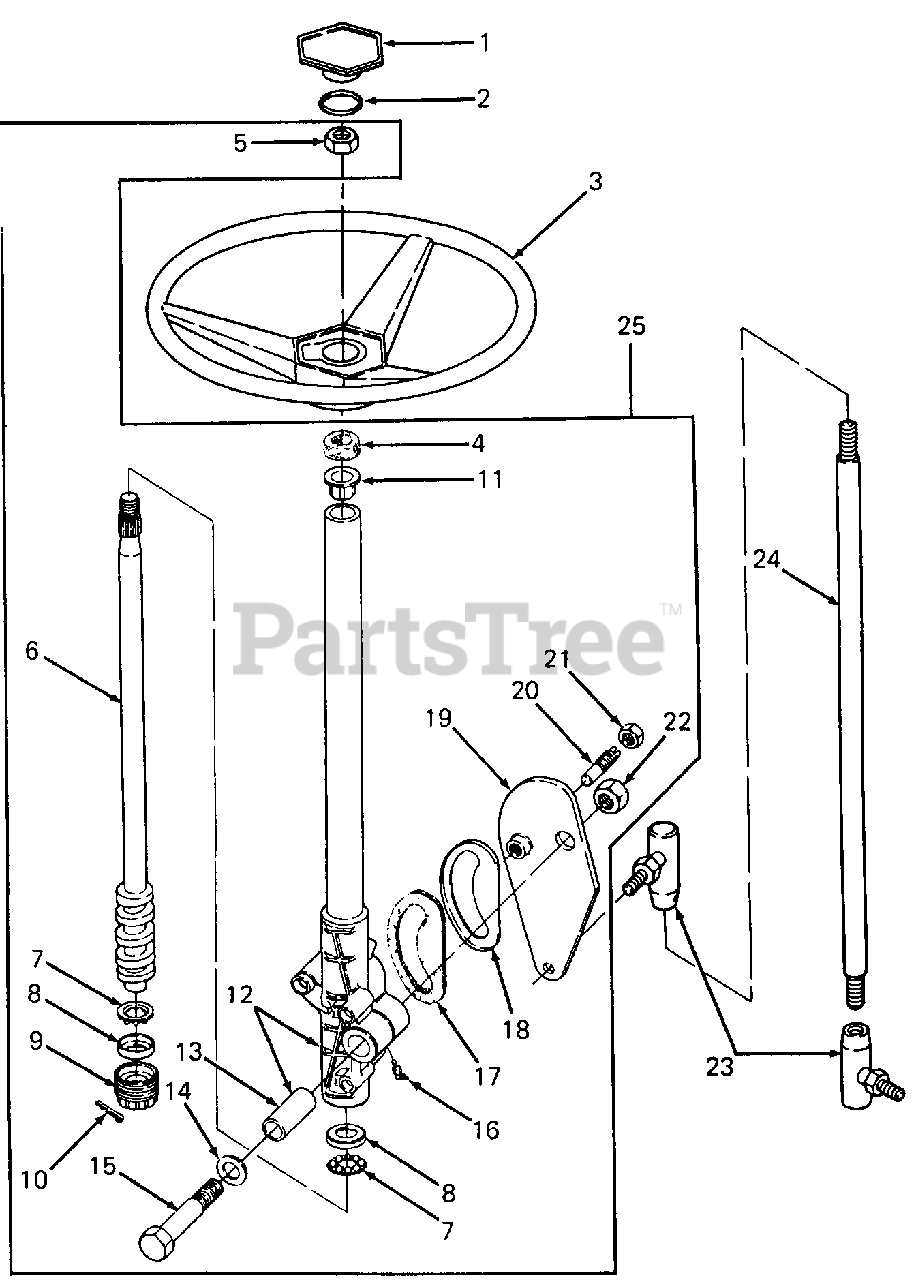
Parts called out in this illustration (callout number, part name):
1	Cap, Steering Wheel
3	Wheel, Steering
4	Seal, Column
5	Nut, Hex Jam, 5/8-18
6	Shaft/Cam Assy
7	Retainer Assy, Ball
8	Cup, Bearing
9	Plug, Adjusting
10	Pin, Cotter, 1/8 Dia X .75 Lg
11	Bearing, Column
12	Housing/Tube Assy
14	Washer, Flat, .781 X 1.25 X .027 Thk
15	Shaft, Pivot
16	Fitting, Lube, 3/16 Drive Type
17	Seal, Grease
18	Retainer, Seal
19	Arm, Steering
20	Follower, Cam
21	Nut, Hex Jam, 9/16-18
22	Nut, Hex Crown Lock, 5/8-18
23	Ball Joint
24	Link, Steering Gear Drag
25	Steering Gear Assy
